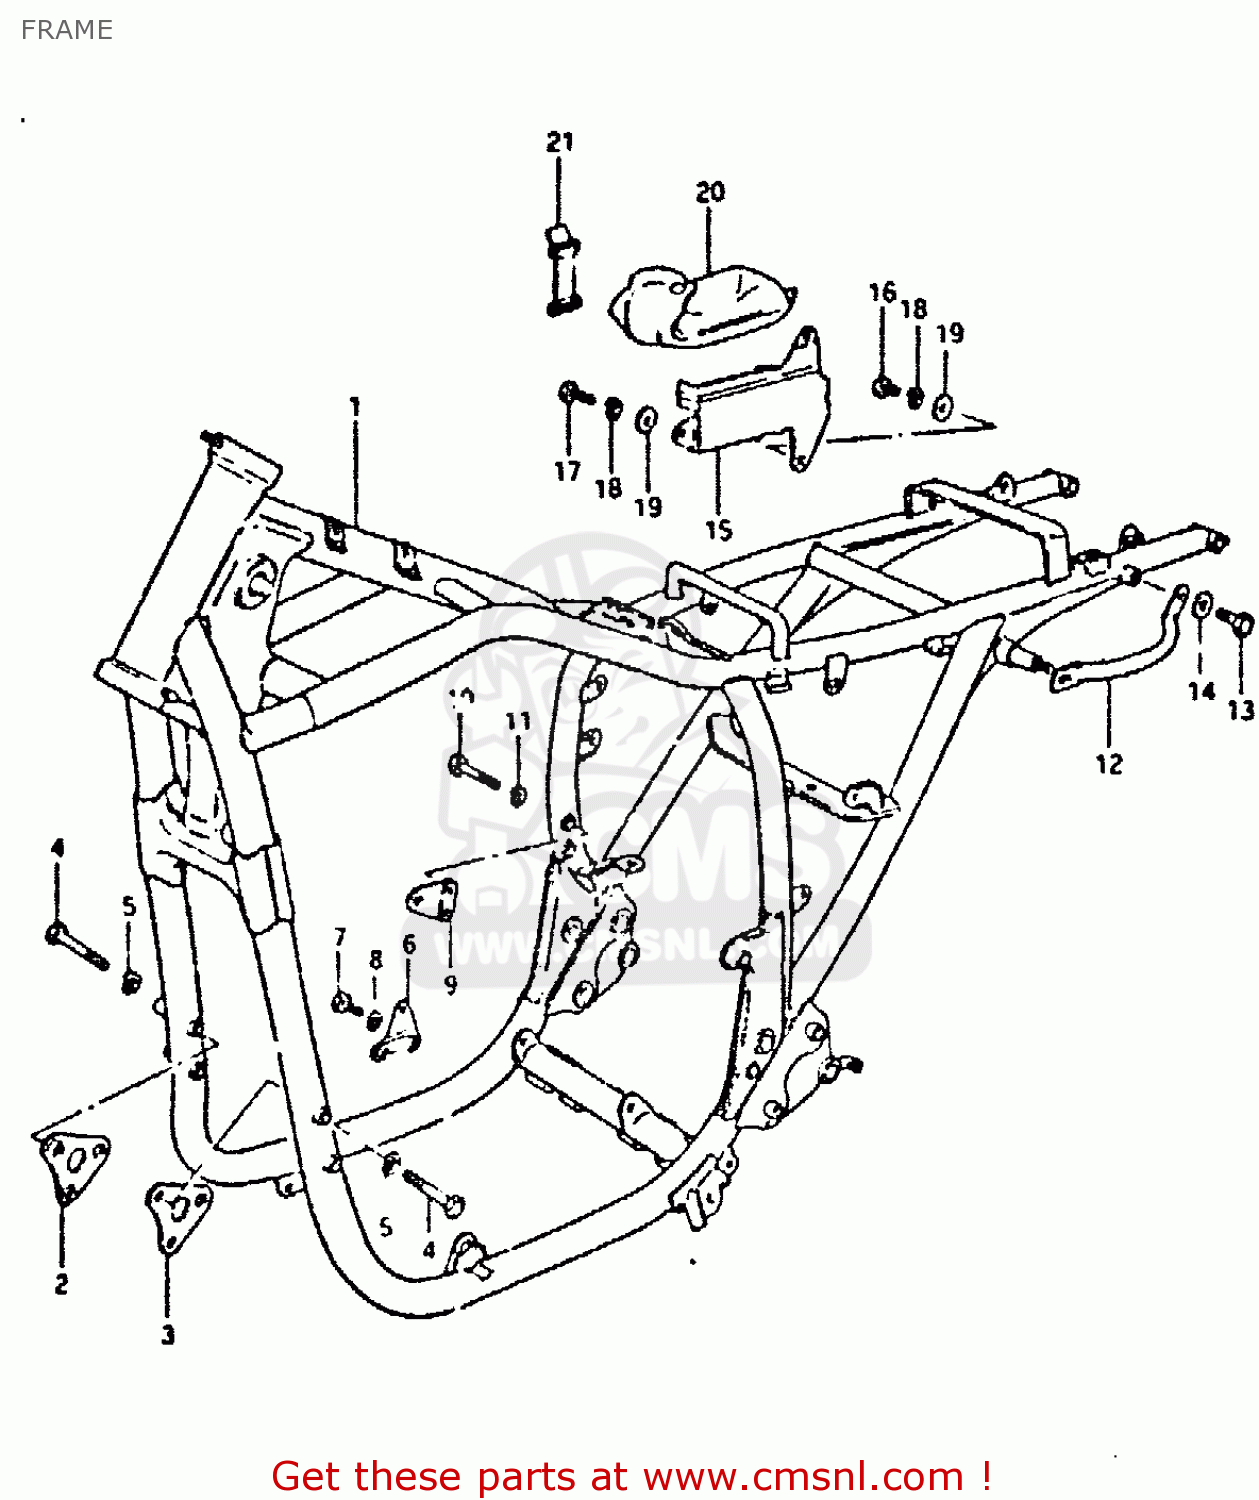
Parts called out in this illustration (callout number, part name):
1	FRAME
2	PLATE,ENGINE MOUNTING
3	PLATE,ENGINE MOUNTING
4	BOLT
5	LOCK WASHER
6	PLATE,ENGINE MOUNTING
7	BOLT
8	LOCK WASHER
9	PLATE,ENGINE MOUNTING
10	BOLT 8X45
11	LOCK WASHER
12	GRIP,FRAME HANDLE
13	BOLT
14	WASHER
15	HOLDER,TOOL
16	SCREW 6X12
17	SCREW
18	LOCK WASHER
19	WASHER
20	TOOL ASSY
21	BAND
